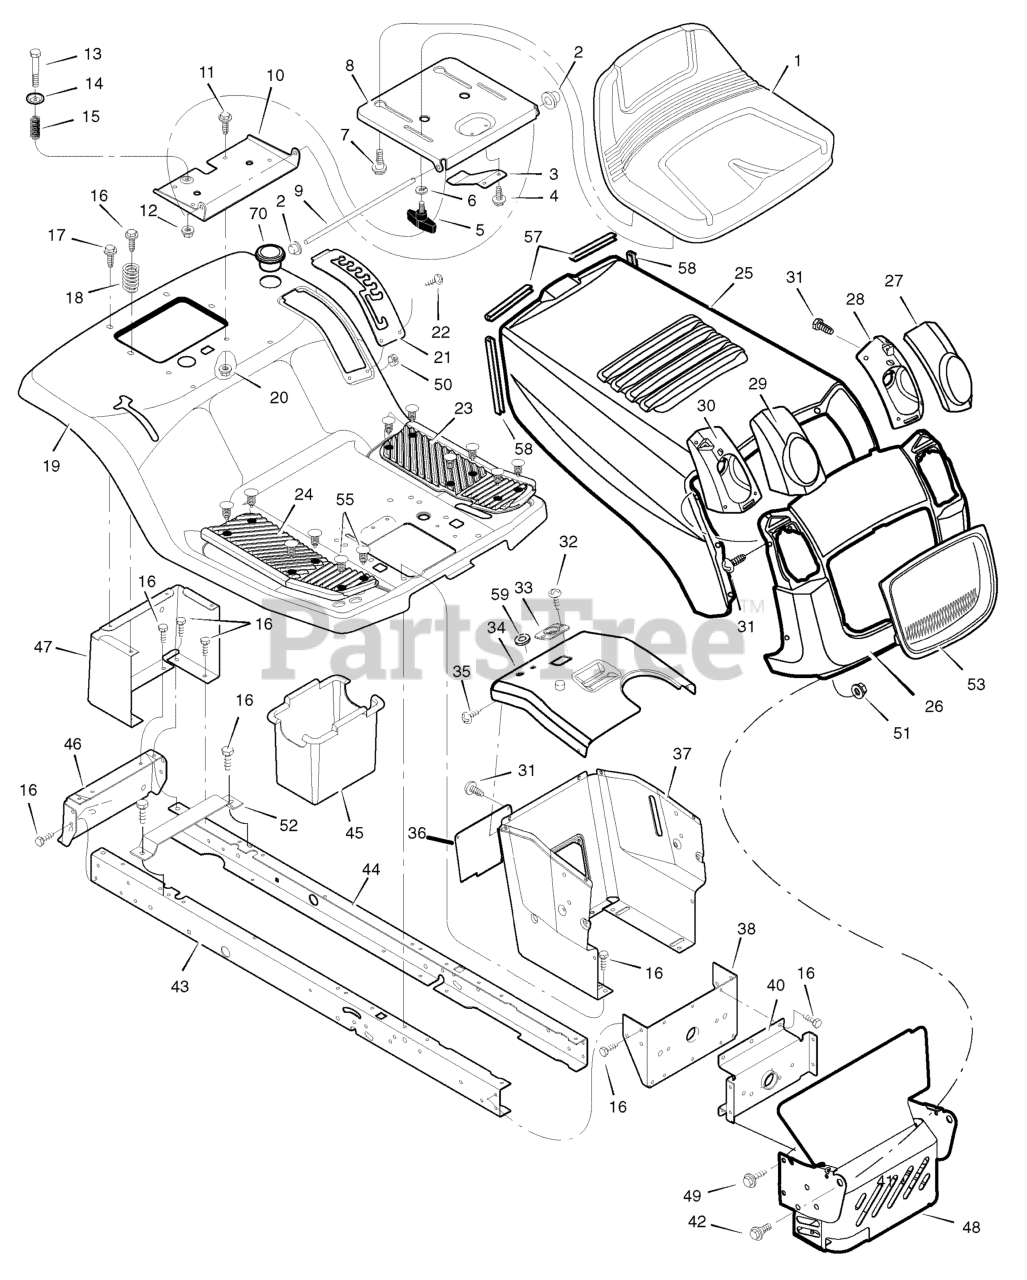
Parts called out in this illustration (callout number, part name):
2	CAP, Push On
5	BOLT, Wing
7	BOLT, Shoulder
8	SUPPORT, Seat
9	ROD, Pivot
10	BRACKET, Seat Pivot
13	BOLT, Shoulder
14	WASHER, Cup
19	DECK, Seat
21	PLATE, Lift
23	MAT, Left
24	MAT, Right
26	GRILLE, X1/X3
27	LENS, Left
28	HOUSING. Left Headlamp
29	LENS, Right
30	Housing, Right Headlamp
33	BEARING, Steering
36	PANEL, Access
37	SUPPORT, Dash
38	BRACKET, Rear Hanger
40	AXLE, Hanger
42	BOLT, Shoulder
43	FRAME, Right
44	FRAME, Left
45	Container, Battery
46	PLATE, Hitch
47	PANEL, Rear
48	SHIELD, Heat
52	SUPPORT, Battery
53	INSERT, Grille
55	FASTENER, Panel
57	TRIM, Hood (3.75")
58	TRIM, Hood (6.5")
59	GROMMET, Parking Brake
70	HOLDER, Cup
